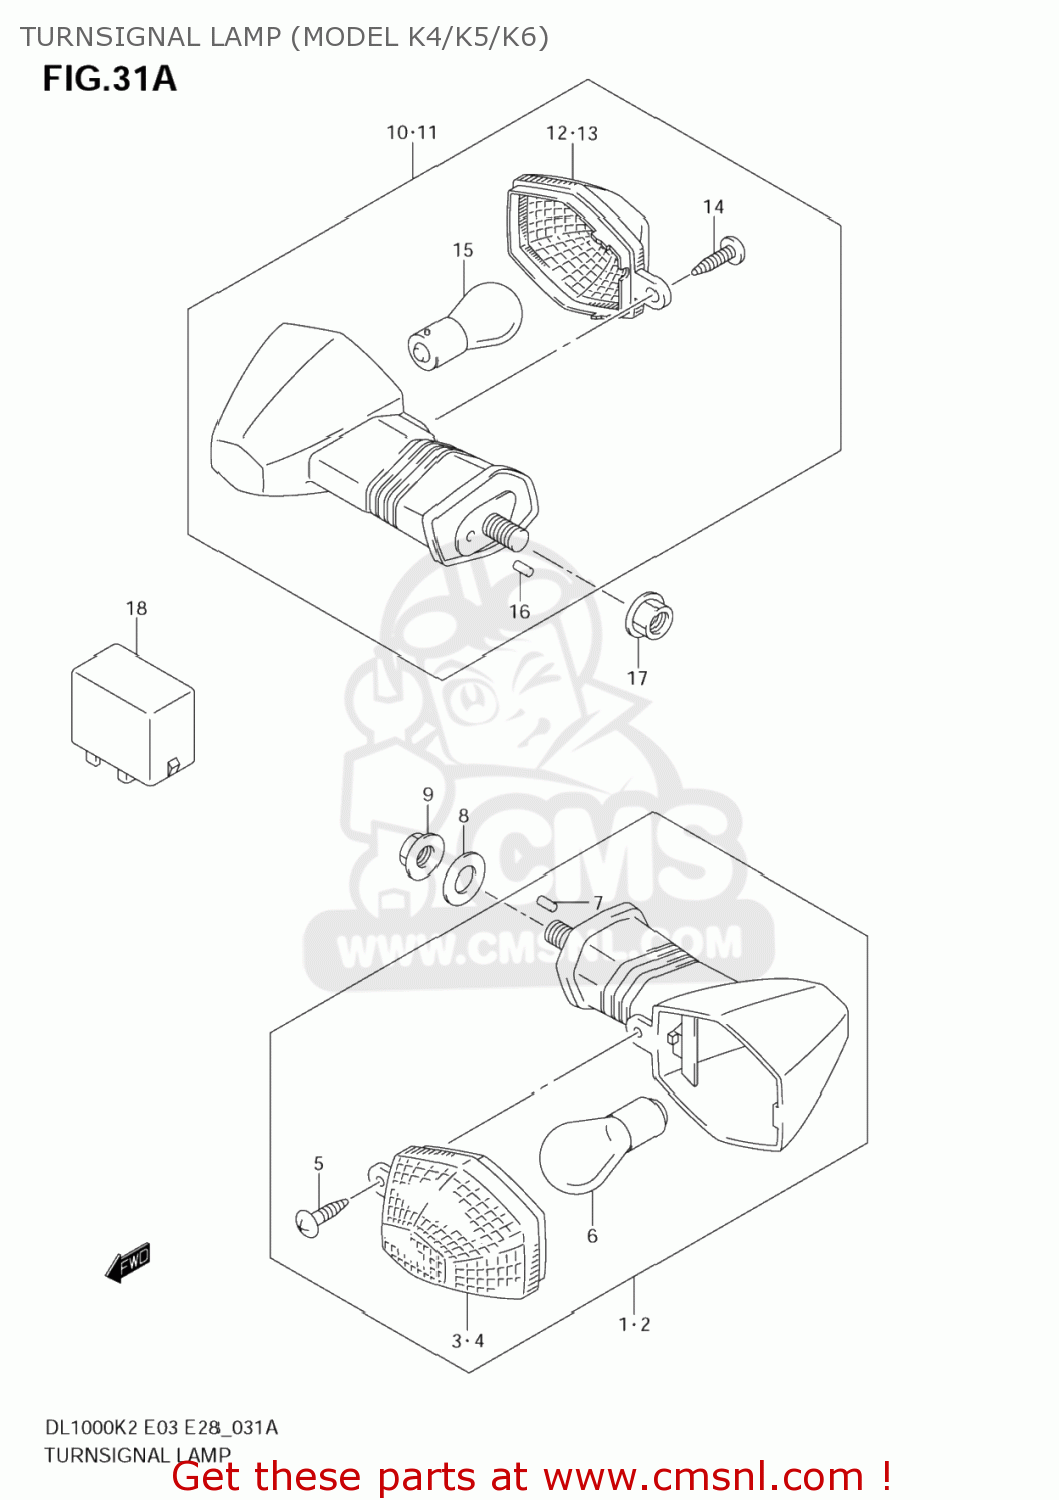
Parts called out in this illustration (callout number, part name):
1	LAMP ASSY,FR TURN SIGNAL,R
2	LAMP ASSY,FR TURN SIGNAL,L
3	LENS
4	LENS
5	SCREW
6	BULB(12V21W)
7	PIN(4.5X9.5)
8	WASHER(12.5X30X1.6)
9	NUT
10	LAMP ASSY,RR TURNSIGNAL,R
11	LAMP ASSY,RR TURNSIGNAL,L
12	LENS
13	LENS
14	SCREW
15	BULB(12V21W)
16	PIN(4.5X9.5)
17	NUT
18	RELAY ASSY,TURNSIGNAL LAMP
